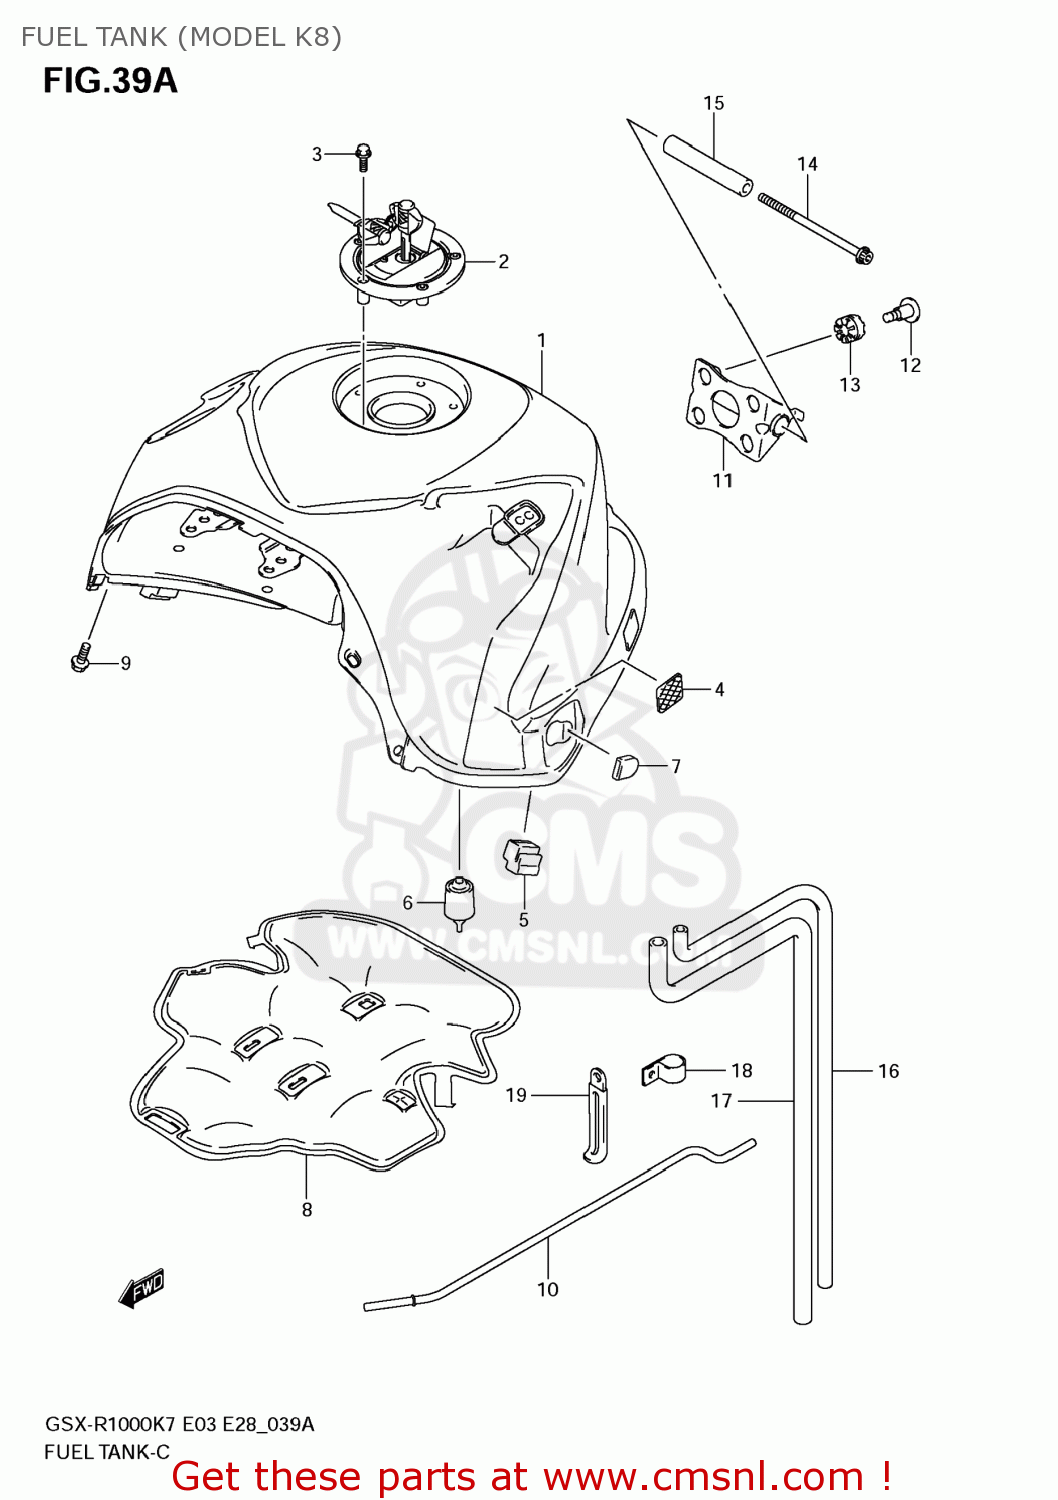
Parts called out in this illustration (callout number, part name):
1	TANK ASSY,FUEL(BLUE)
2	CAP SET,FUEL TANK
3	BOLT(5X20)
4	FASTENER
5	CUSHION,FUEL TANK SIDE
6	CUSHION,FUEL TANK RR
7	CUSHION
8	SHIELD,FUEL TANK HEAT
9	SCREW(6X10)
10	STAY,FUEL TANK
11	BRACKET,FUEL TANK NO.1
12	SCREW,FUEL TAN
13	CUSHION
14	BOLT(6X110)
15	SPACER,FUEL TANK RR
16	HOSE,FUEL TANK WATER DRAIN
17	HOSE,FUEL TANK BREATHER
18	CLAMP
19	CLAMP(L:80)
